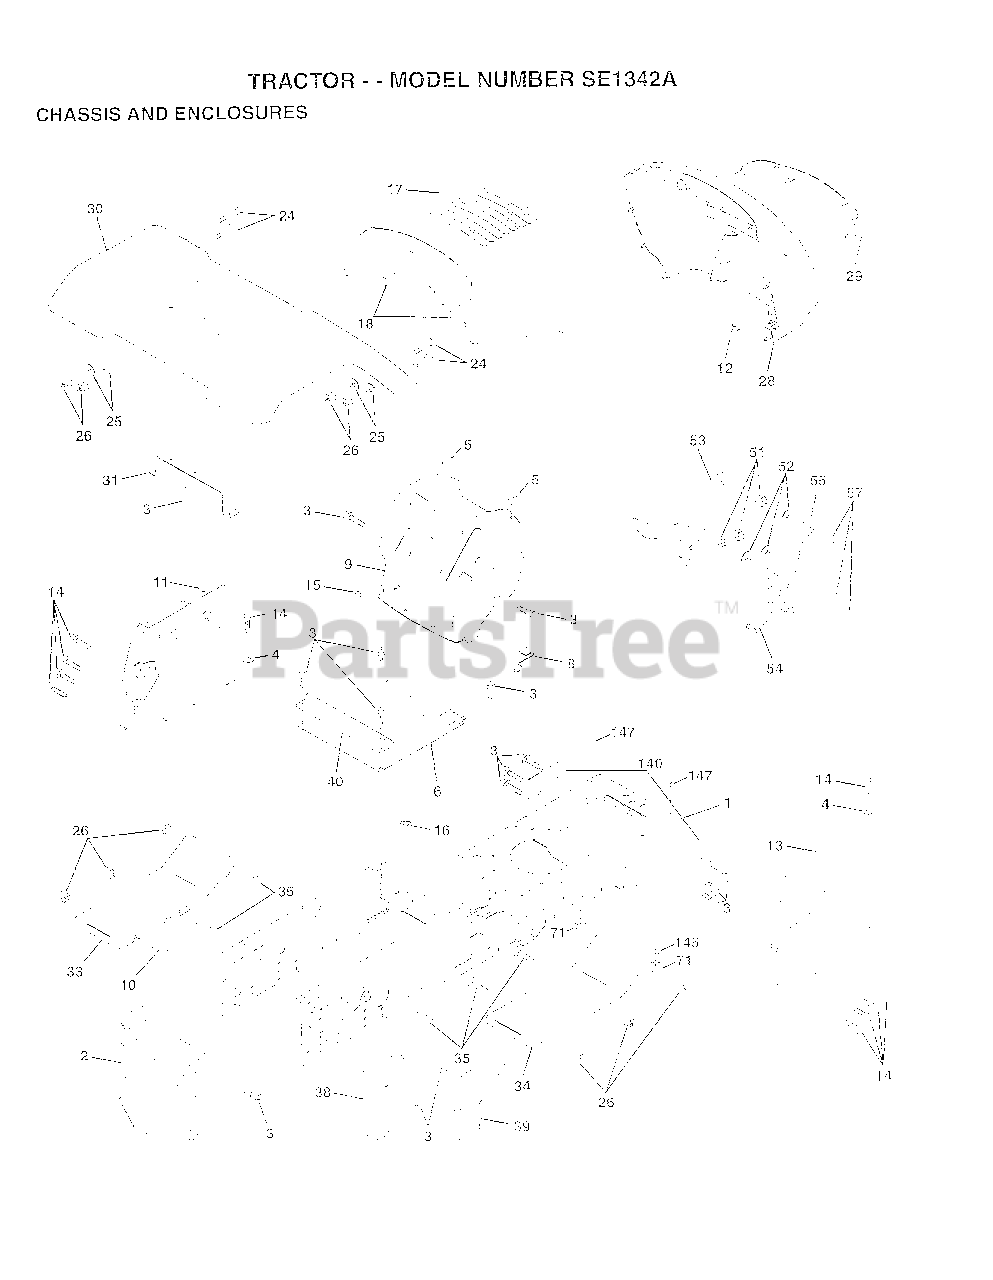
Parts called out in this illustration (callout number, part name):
1	CHASSIS ASM
3	SCREW
4	WASHER
5	BUMPER-HOOD/DASH
6	SADDLE
8	"CLIP,INSULATOR"
9	DASH.SILKSCREENED
11	"PANEL-DASH,LH"
12	CLIP.TINNERMAN
14	SCREW LT
15	BOLT
18	MANUAL
24	BOLT
25	WASHER
26	NUT
28	GRILLE-MS428
29	LENS GRILLE
30	FENDER LT
31	BRACKET SUPT FEND
33	FOOTREST LH
34	FOOTREST RH
35	BOLT
38	BRACKET ASM LH
39	BRACKET ASM RH
40	SPACER FENDER LT
51	NUT
52	WASHER
53	BRACKET.GRILLE.LH
55	BRACKET.GRILLE.RH
140	BRKT SUSPENSION
145	"ROD POVOT,CHASSIS"
147	BOLT LT
